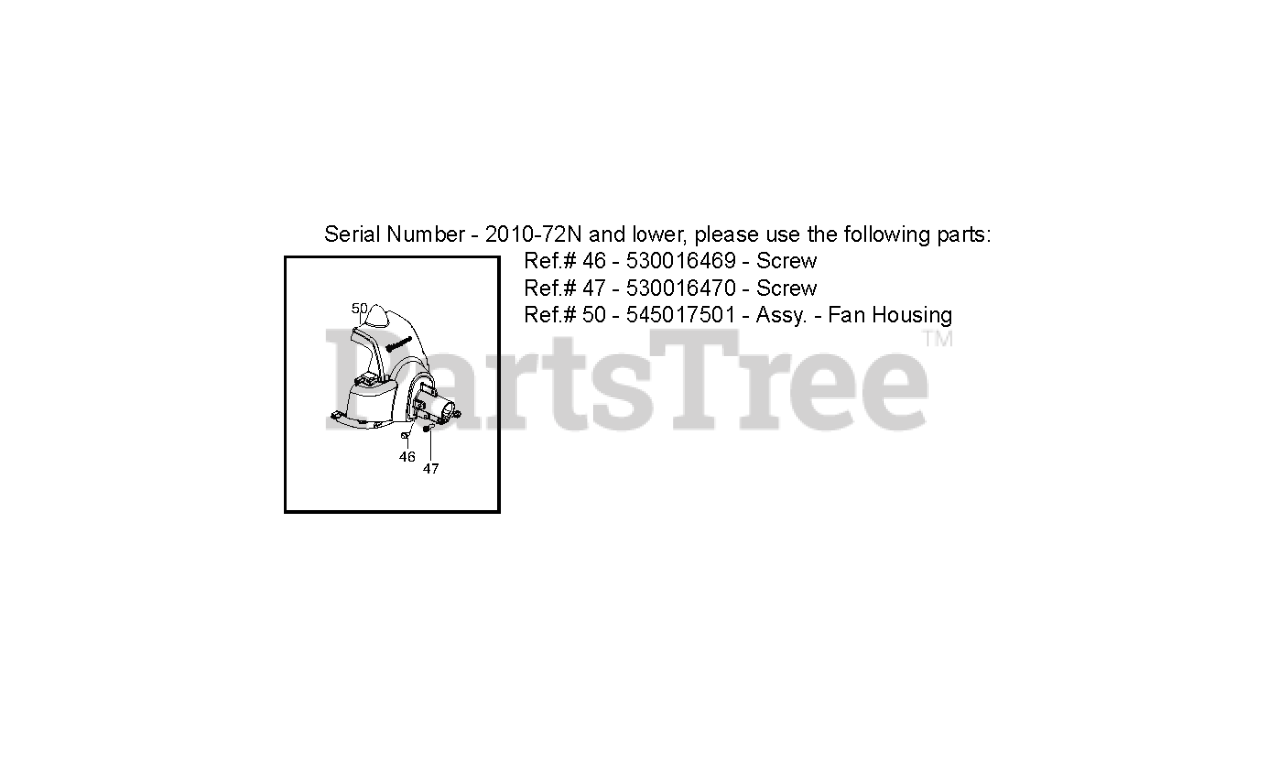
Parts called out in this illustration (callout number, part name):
46	SCREW
47	SCREW
50	FAN HSG ASSY
